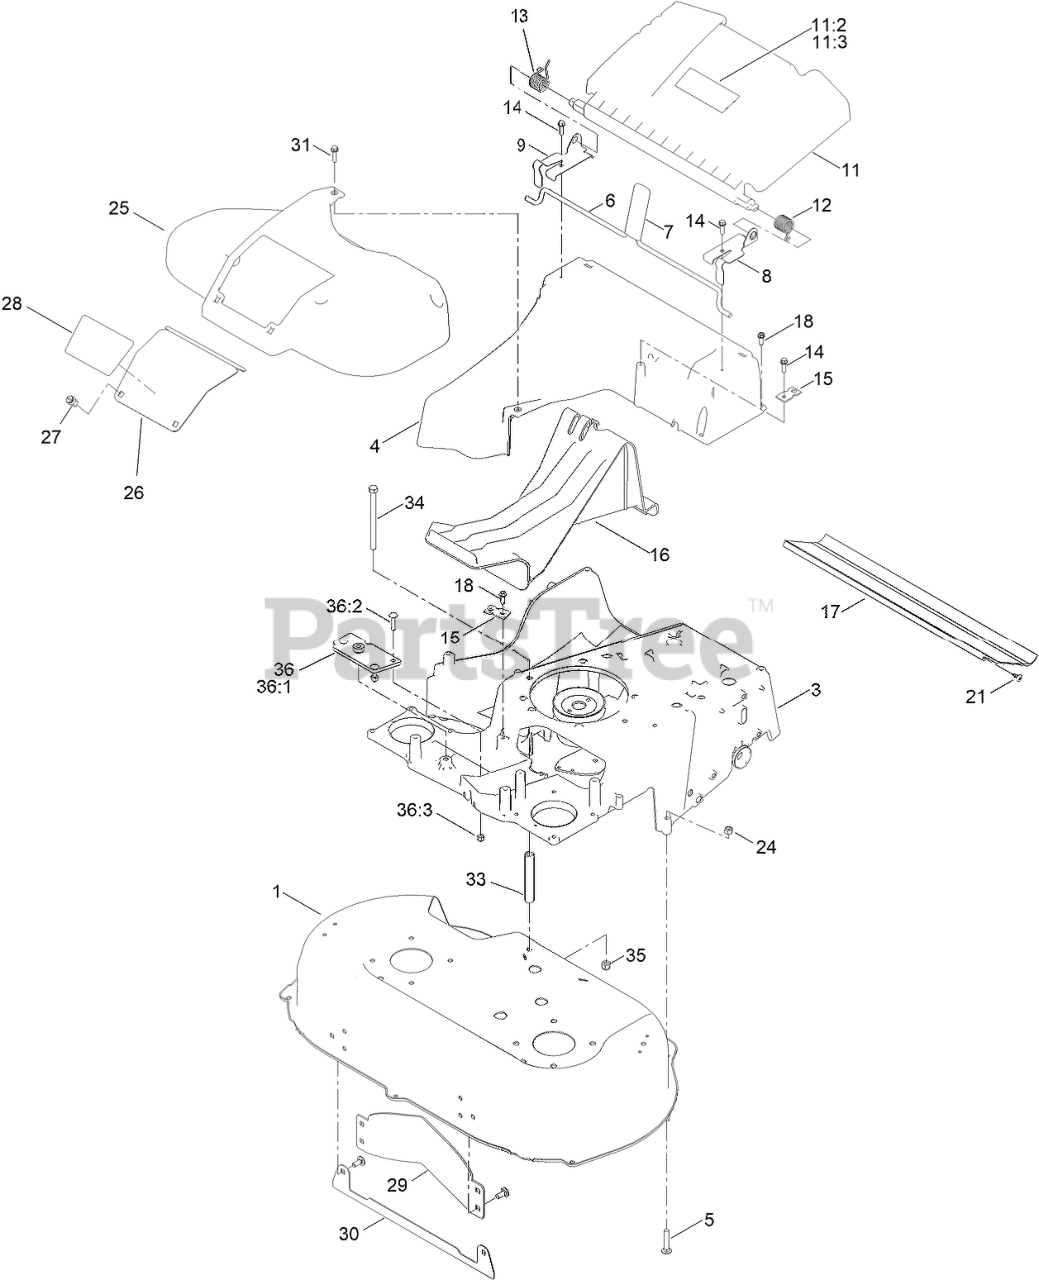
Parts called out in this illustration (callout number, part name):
1	HOUSING ASM
3	FRAME-30"
5	BOLT-CAR
6	ROD-RELEASE, HANDLE
7	GRIP-LEVER
8	BRACKET-DOOR, LH
9	BRACKET-DOOR, RH
11	REAR DEFLECTOR ASM
11:2	ARTWORK-WARNING
11:3	DECAL-WARNING
12	SPRING-TORSION
13	SPRING-TORSION
14	SCREW-PLASTITE, HWH
15	BRACKET-CABLE, TRACTION
16	PLUG-MULCH
17	SHIELD-TRAILING
18	SCREW-HWHTF
21	SCREW-THD
24	NUT-HEX
25	COVER-BELT
26	DOOR-ACCESS
27	FASTENER
28	DECAL-ACCESS PANEL
29	BAFFLE-CONTROL
30	PLATE-DECK
31	SCREW-HWHTF
33	SPACER-SHIELD
34	SCREW-HH
35	NUT-HEX
36	FRAME PLATE KIT
36:1	PLATE-FRAME
36:2	SCREW-CARR
36:3	NUT-LOCK, NI
